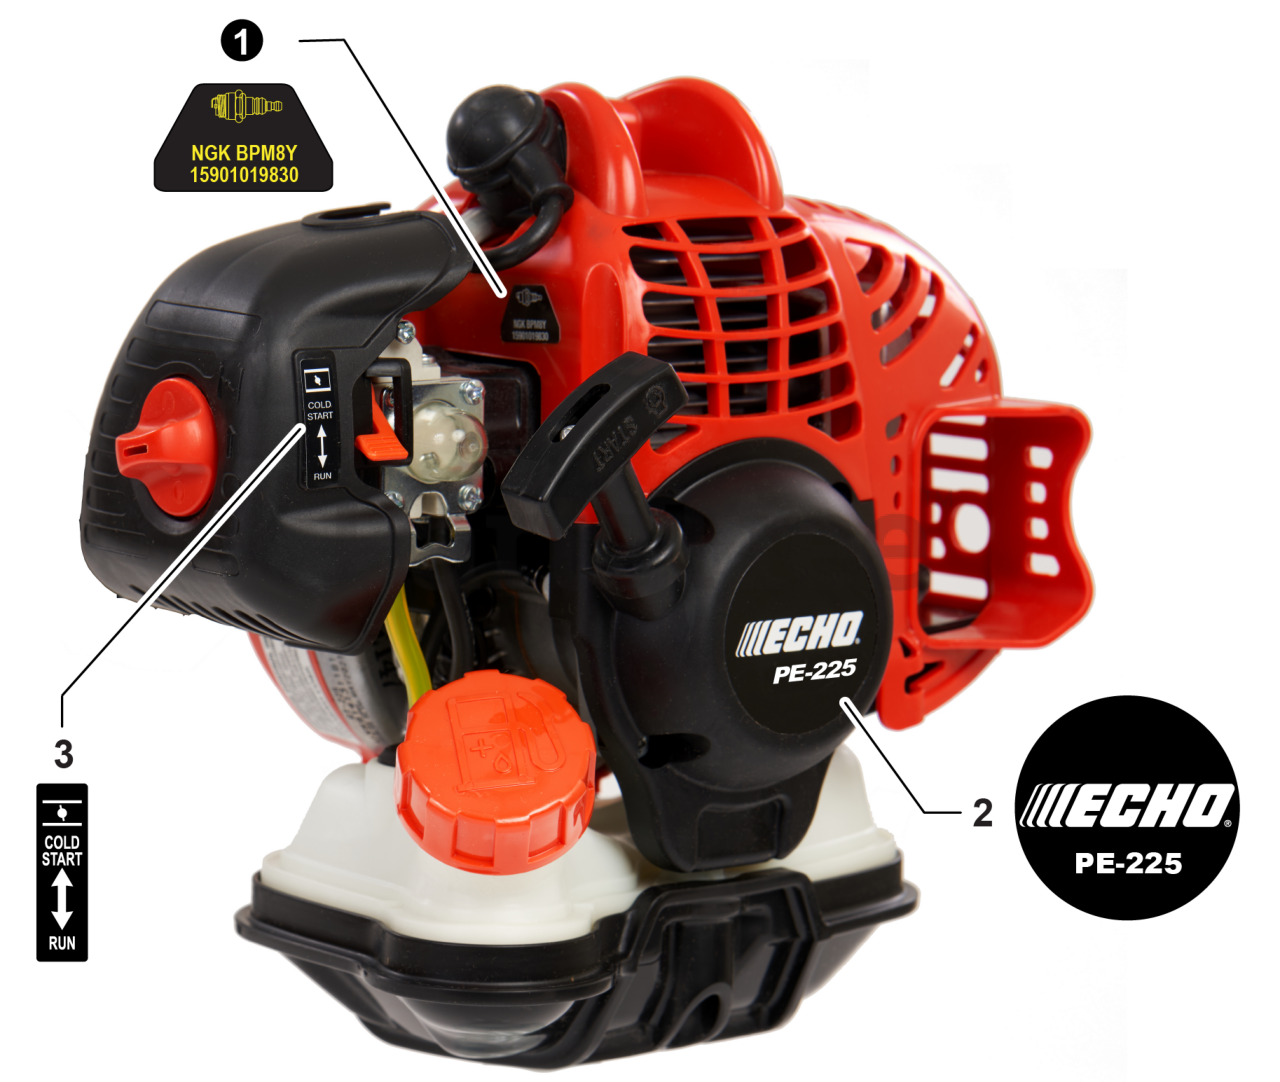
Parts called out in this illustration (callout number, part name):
1	LABEL - SPARK PLUG - BPM8Y
2	LABEL - MODEL - PE-225
3	LABEL - CHOKE
